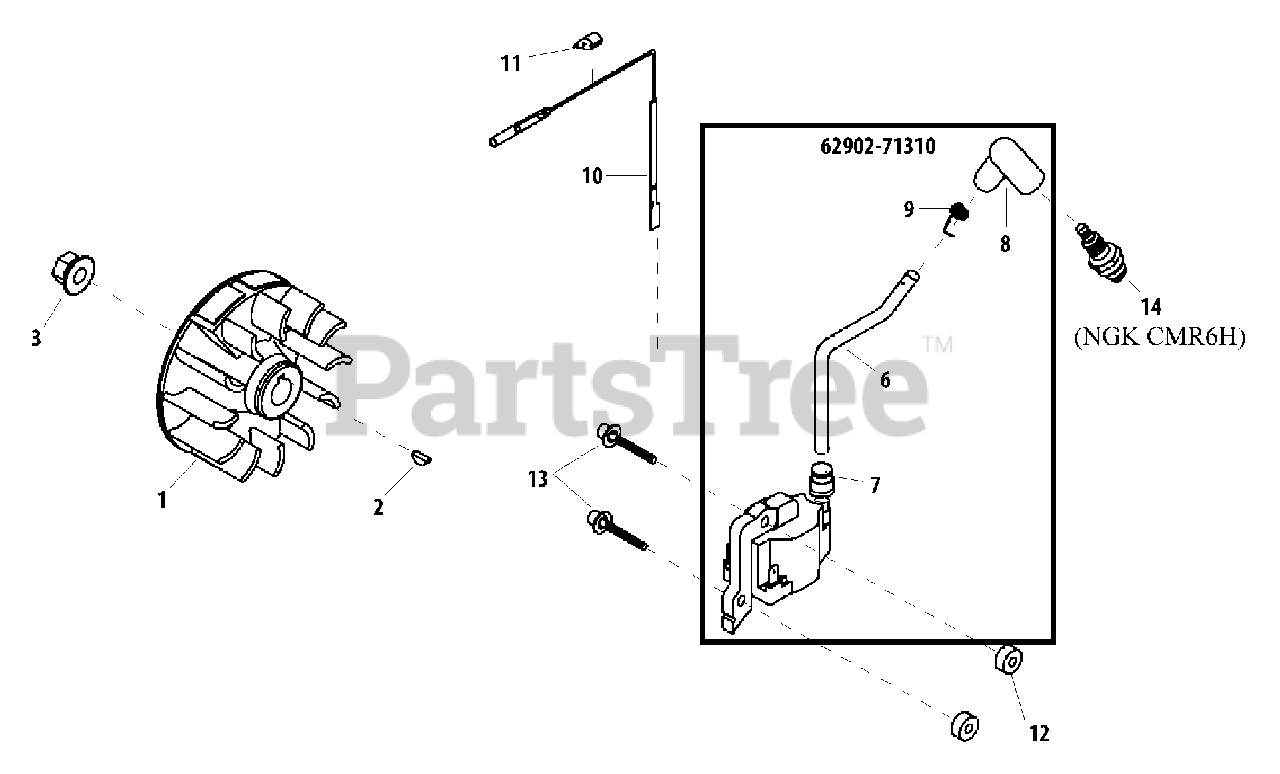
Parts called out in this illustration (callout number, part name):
1	FLYWHEEL
2	KEY, WOODRUFF 3×10
3	NUT M8
7	GROMMET
8	CAP, SPARK PLUG
9	TERMINAL, SPARK PLUG
10	LEAD
11	GROMMET, LEAD
12	INSULATOR 4.2×11×6
13	BOLT M4×26
14	SPARK PLUG
62902-71310	IGNITION COIL ASSY
